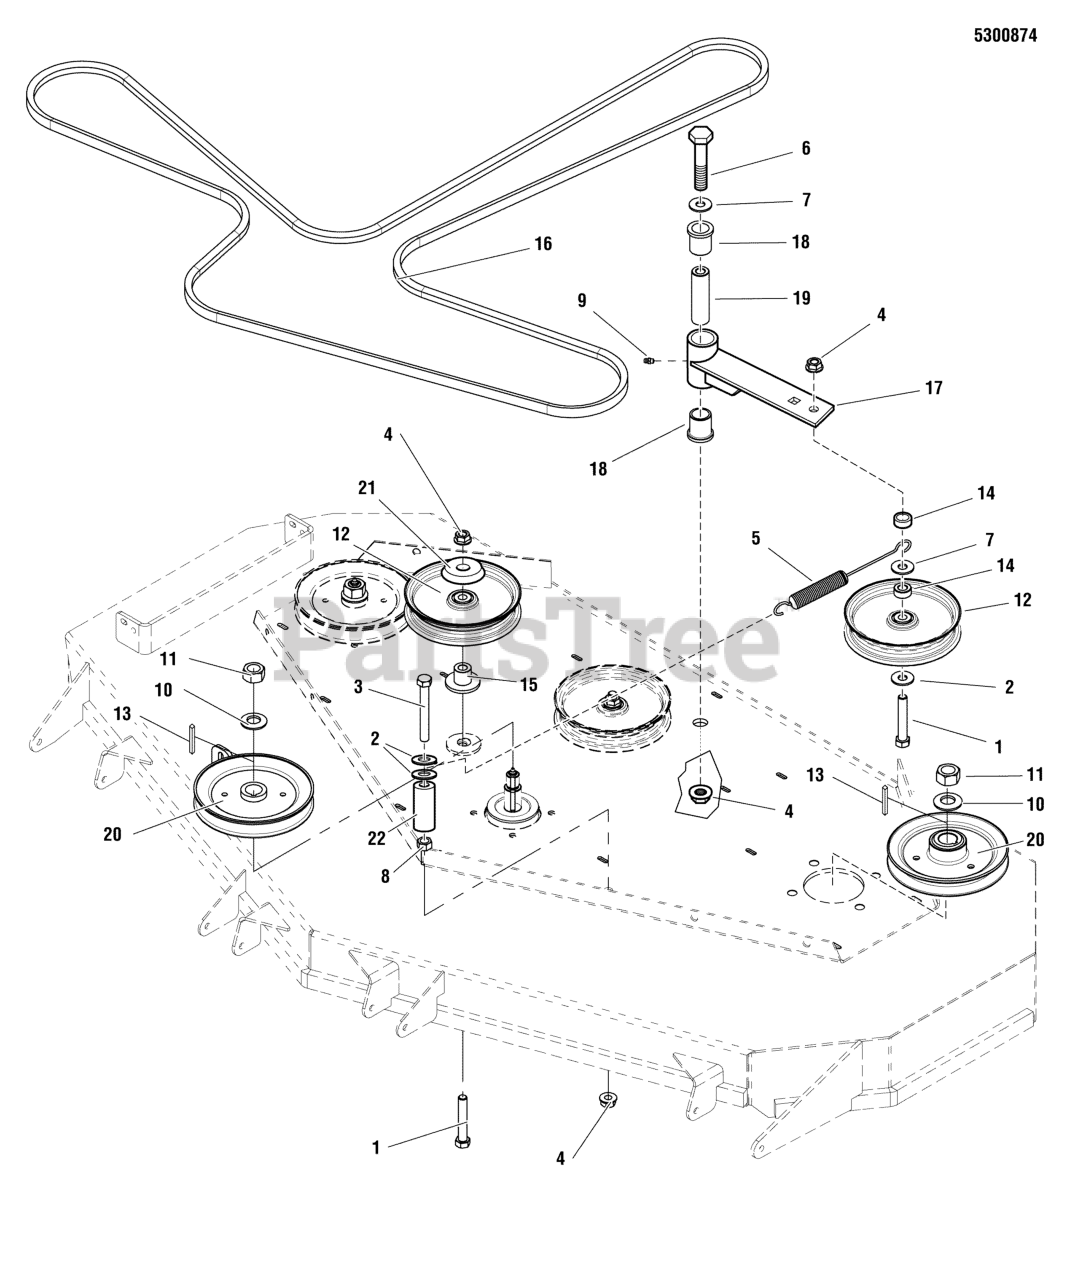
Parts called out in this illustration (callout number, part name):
1	BOLT, 1/2-13 X 3" GD5 CZ
2	WASHER, 1/2 SAE
3	BOLT, 1/2-13 X 4" GD5 CZ
4	NUT, Hex Flange, Nylock, 1/2-13
5	SPRING, EXTENSION, SWIVEL END
6	BOLT, 1/2-13 X 4-1/2 GD5
7	WASHER, 1/2 USS
8	NUT, 1/2-13 HEX
9	GREASE FITTING, 1/4-28 STRAIGHT
10	WASHER, 3/4 BELLEVILLE
11	NUT, 3/4-16 HEX
13	KEY, 1/4 SQ. X 1-1/4
14	SPACER, .52 X 1.00 X .38
15	IDLER MOUNT
16	BELT, BP-SEC, 167.88EL, ARAMID, WRPD
17	ASSM, IDLER ARM
18	BUSHING, FLANGE
19	SPACER, .52 X 1.00 X 3.50
20	PULLEY, SPIN, 6.5 OD X 25MM,
21	SHIELD, PULLEY BEARING
22	HOSE, 1/2-13 X 4 GD5 YZ
